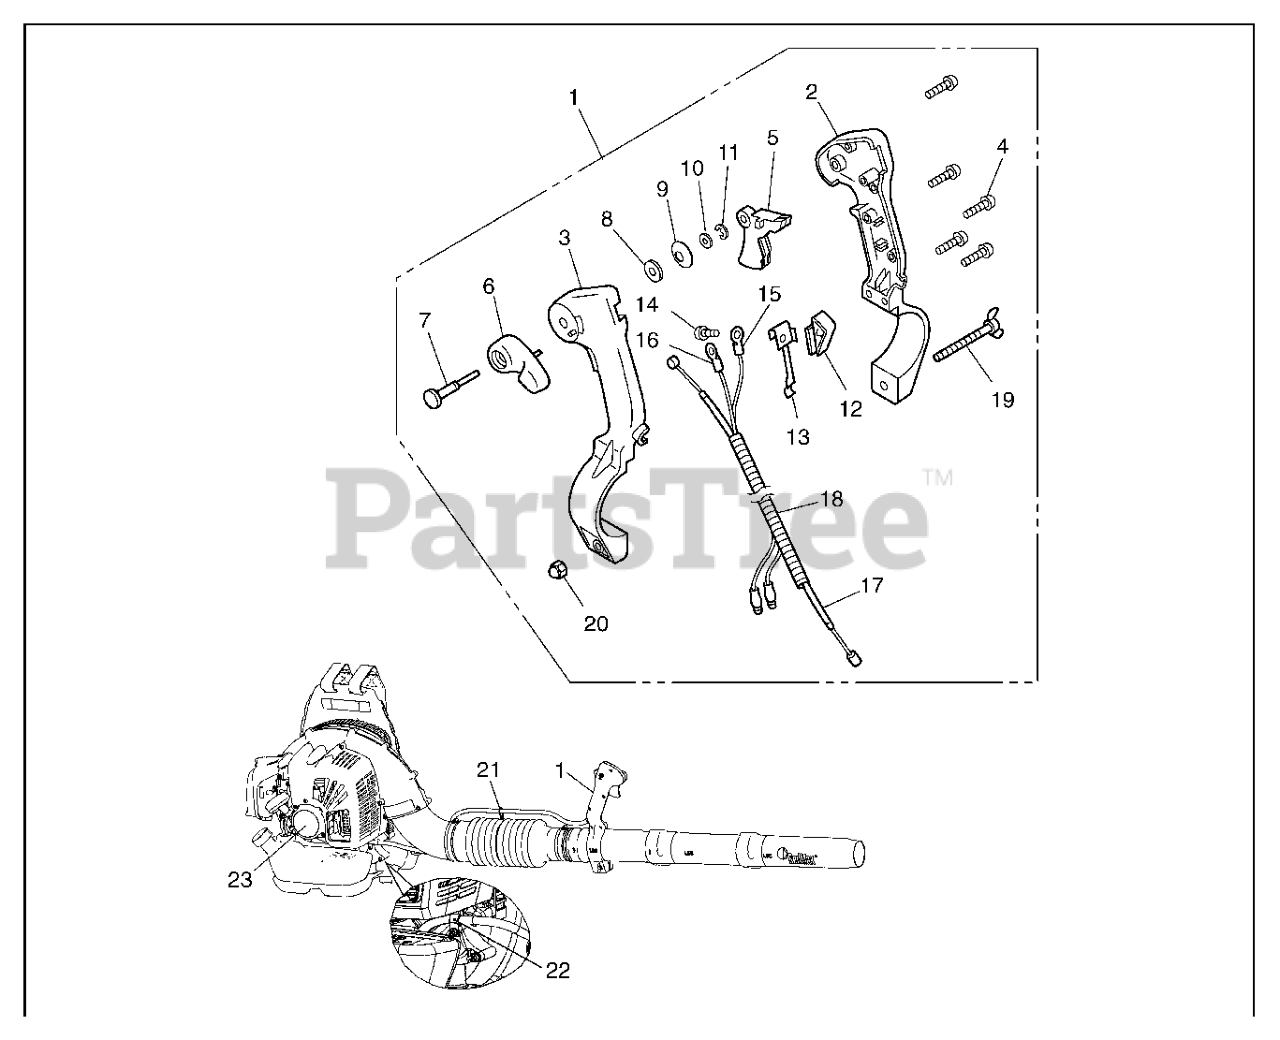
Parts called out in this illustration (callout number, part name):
1	LEVER(R)SET
4	SCREW 4X14(T)
5	LEVER THROTTLE
6	RP_LEVER (RPLS T402325430)
7	SHAFT
8	WASHER(T)
9	RP_SPRING WASHER
10	WASHER
11	RP_CLIP(T)
12	SWTICH (T)
13	SPRING (RPLS T402325720)
14	RP_SCREW 4X10(T)
15	CORD, RED
16	CORD, RED
19	BOLT WING
23	RECOIL DECAL
